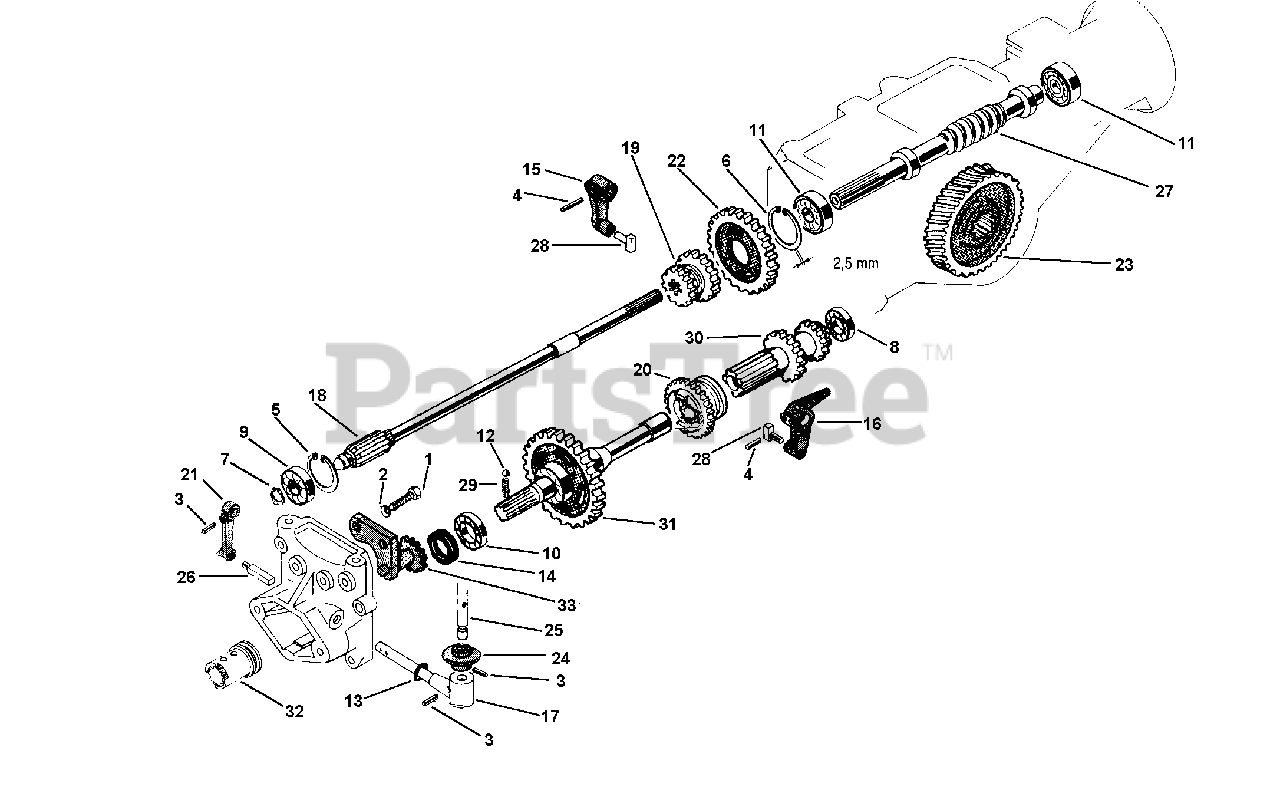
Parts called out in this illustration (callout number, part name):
1	SCREW M10 X 30
2	SUPER WASHER 10
3	LOCKING PIN 4 X 20 SPIRAL
4	LOCKING PIN 4 X 24 SPIRAL
5	CIRCLIP, INTERNAL
6	CIRCLIP INTERNAL
9	BEARING 15 X 42 X 13
10	BEARING 25 X 52 X 15
14	OIL SEAL 25 X 40 X 7
15	LEVER, SPEED CHG SLDG GR
16	LEVER, REVERSER
17	PTO CONTROL PIN
18	MAIN DRIVE SHAFT
19	DOUBLE SLIDER
20	SLIDER, REVERSER
22	WHEELS FIRST SPEED
23	GEAR Z 49, LH MOTOR MOWER
24	PTO STOP RING
25	PTO CONTROL LEVER
30	SECOND GEAR
32	PTO COUPLING
33	GEAR, REVERSER
